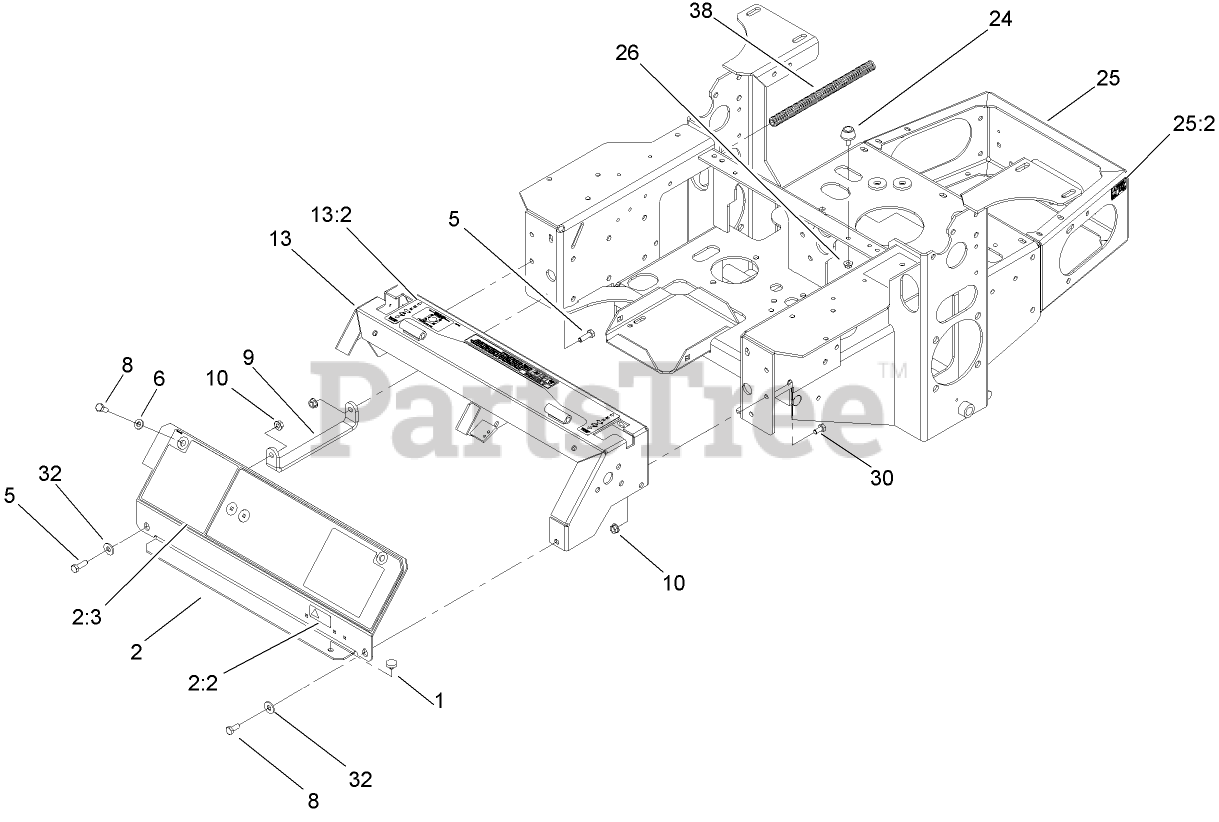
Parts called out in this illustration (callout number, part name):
1	BUMPER
2	PANEL ASM
2:2	DECAL-PROTECTION, EAR
2:3	DECAL-COVER, PANEL
5	SCREW-HH
6	WASHER-PLAIN
8	SCREW-HH
9	BRACKET-PANEL, INSTRUMENT
10	NUT-HF
13	CONSOLE ASM
13:2	DECAL-WARNING
24	BUMPER-RUBBER
25	MAIN FRAME ASM
25:2	DECAL-SURFACE, HOT
26	NUT-HF
30	SCREW-HH
32	WASHER-FLAT
38	CONDUIT-CONVOLUTED, SPLIT
